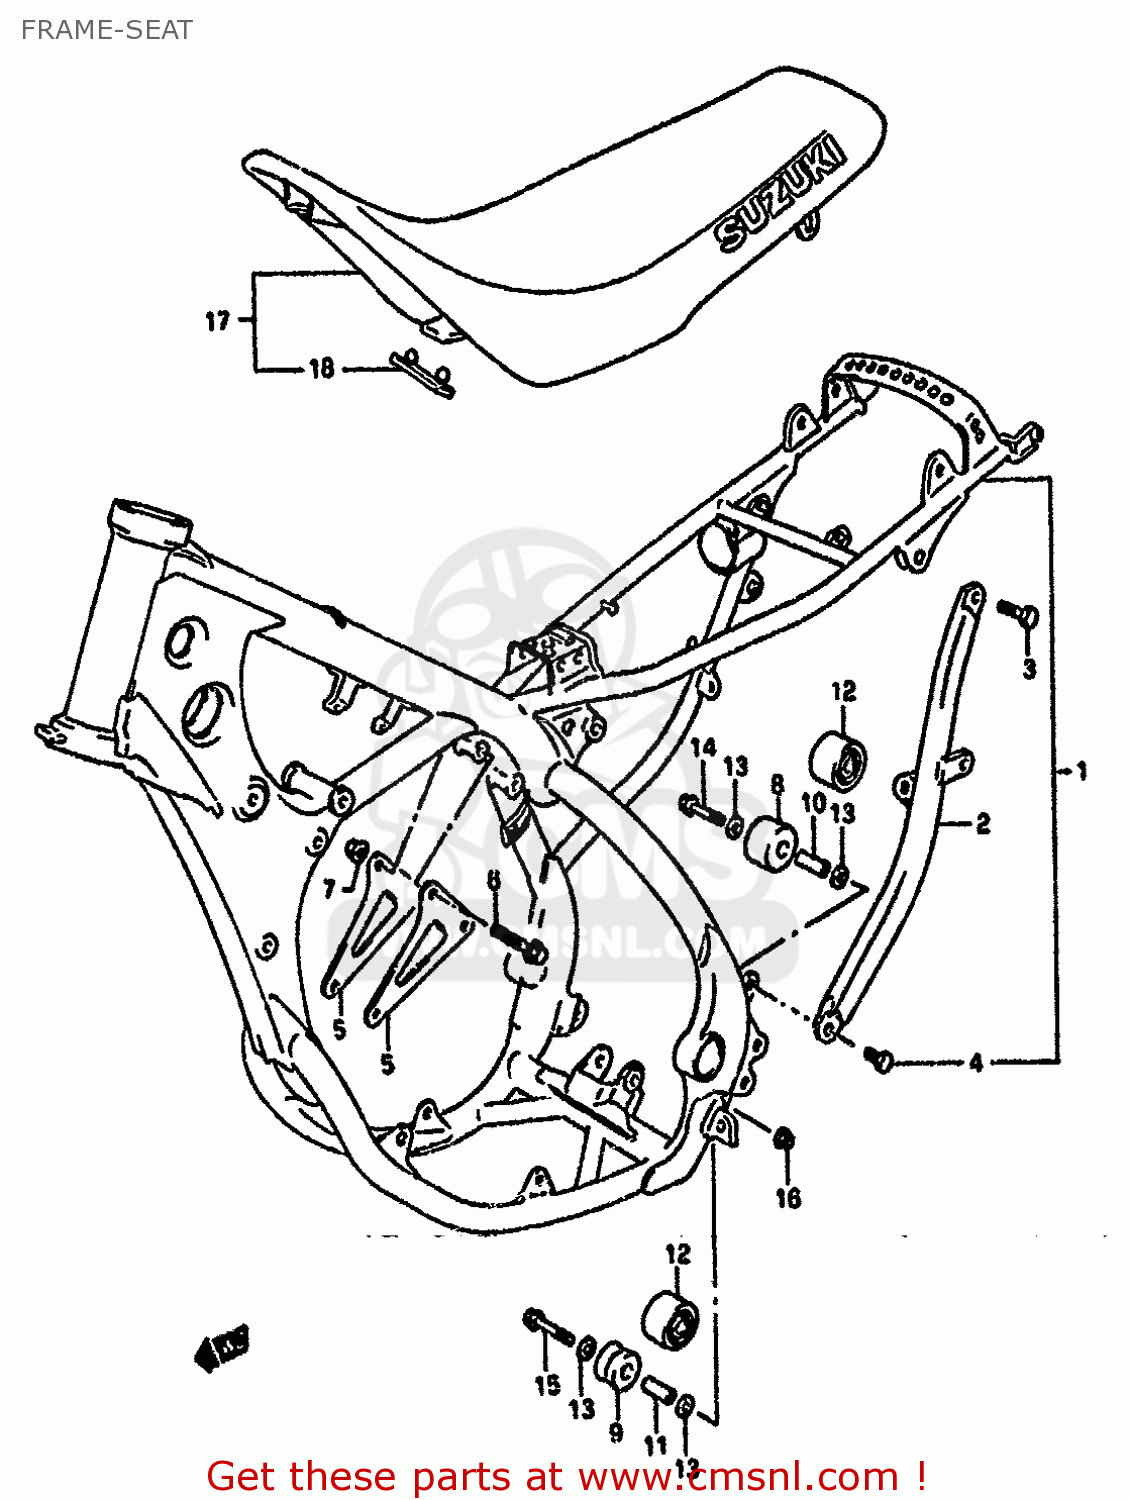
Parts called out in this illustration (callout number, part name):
1	FRAME
2	TUBE,FRAME SIDE,LEFT
3	BOLT(8X22)
4	BOLT
5	PLATE,ENG MTG UPR
6	BOLT(8X41)
7	NUT
8	ROLLER,CHAIN CONTROL
9	ROLLER,CHAIN CONTROL
10	SPACER (8.6X13.8X28)
11	SPACER(8.6X12X25.5)
12	ROLLER,CHAIN
13	WASHER
14	BOLT(8X41)
15	BOLT(8X45)
16	NUT
17	SEAT SET
18	CUSHION
